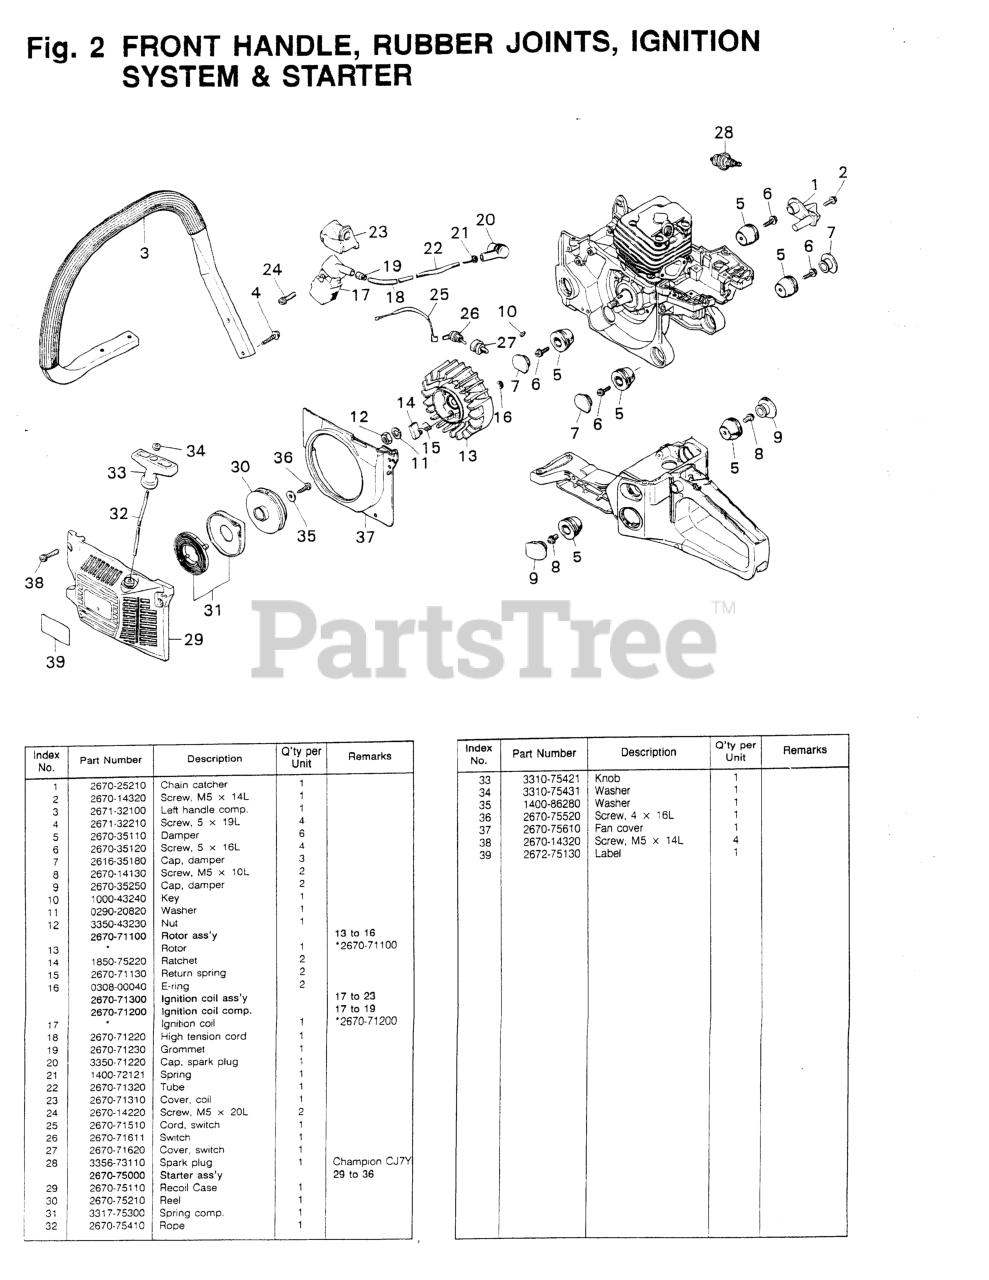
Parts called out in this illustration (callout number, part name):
2	SCREW (REPLACES 2616-24320)
4	SCREW (USE 848-825-1901)
8	SCREW
9	CAP, DAMPER
10	KEY
11	WASHER, M8 x 20
13	ROTOR ASSEMBLY
15	SPRING, RETURN
16	RING, SNAP, M4
20	PLUG CAP
21	SPRING PLUG (RPLS 3310-71320)
23	COVER, COIL (RPLS -71300)
31	SPRING COMP
35	WASHER (USE 181741)
38	SCREW (REPLACES 2616-24320)
39	LABEL, RECOIL CASE (NLA)
NI	STARTER ASSEMBLY
